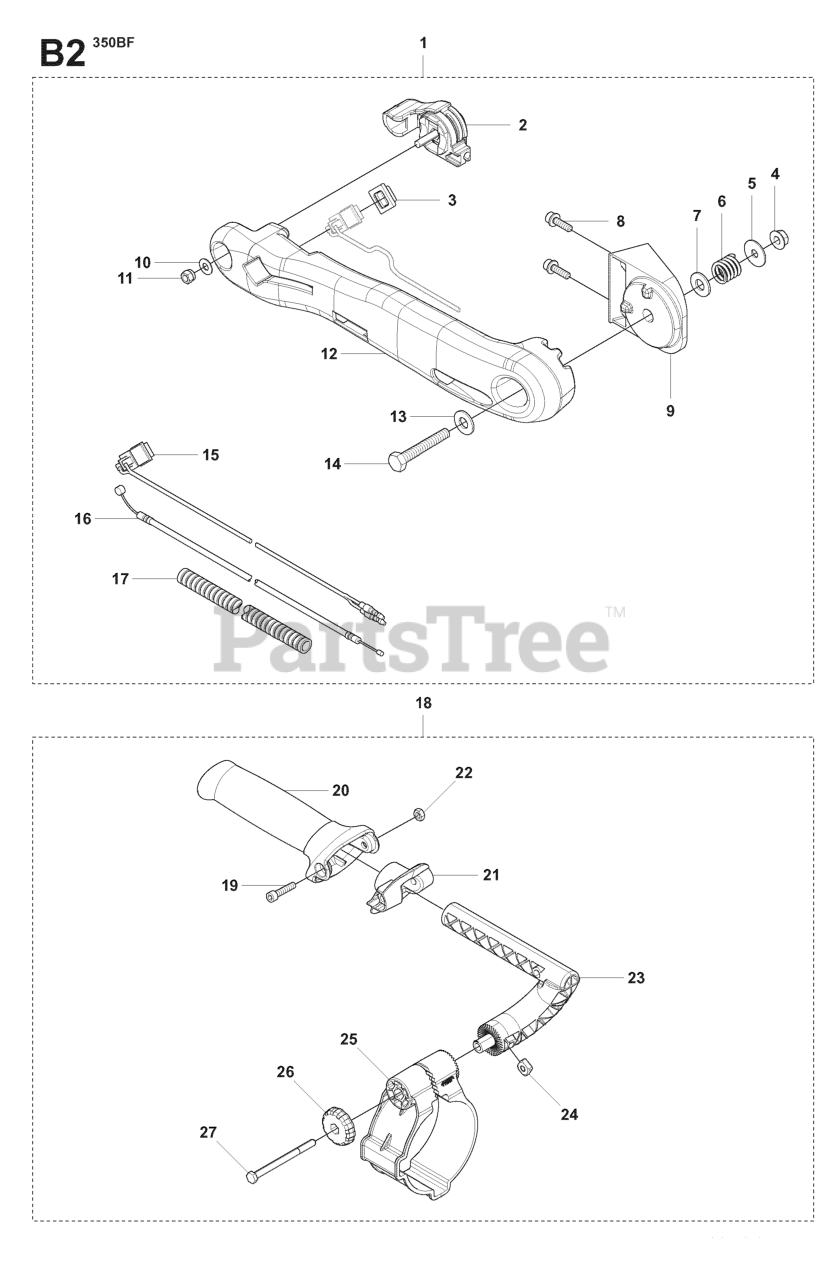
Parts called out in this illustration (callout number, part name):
1	HANDLE ASSY
3	CAP SWITCH
4	NUT 8488646000
5	WASHER Z349525440
10	WASHER
15	KILL SWITCH
16	RP_CABLE COMP
22	NUT
23	BRACKET
24	SQUARE NUT M5
26	KNOB
